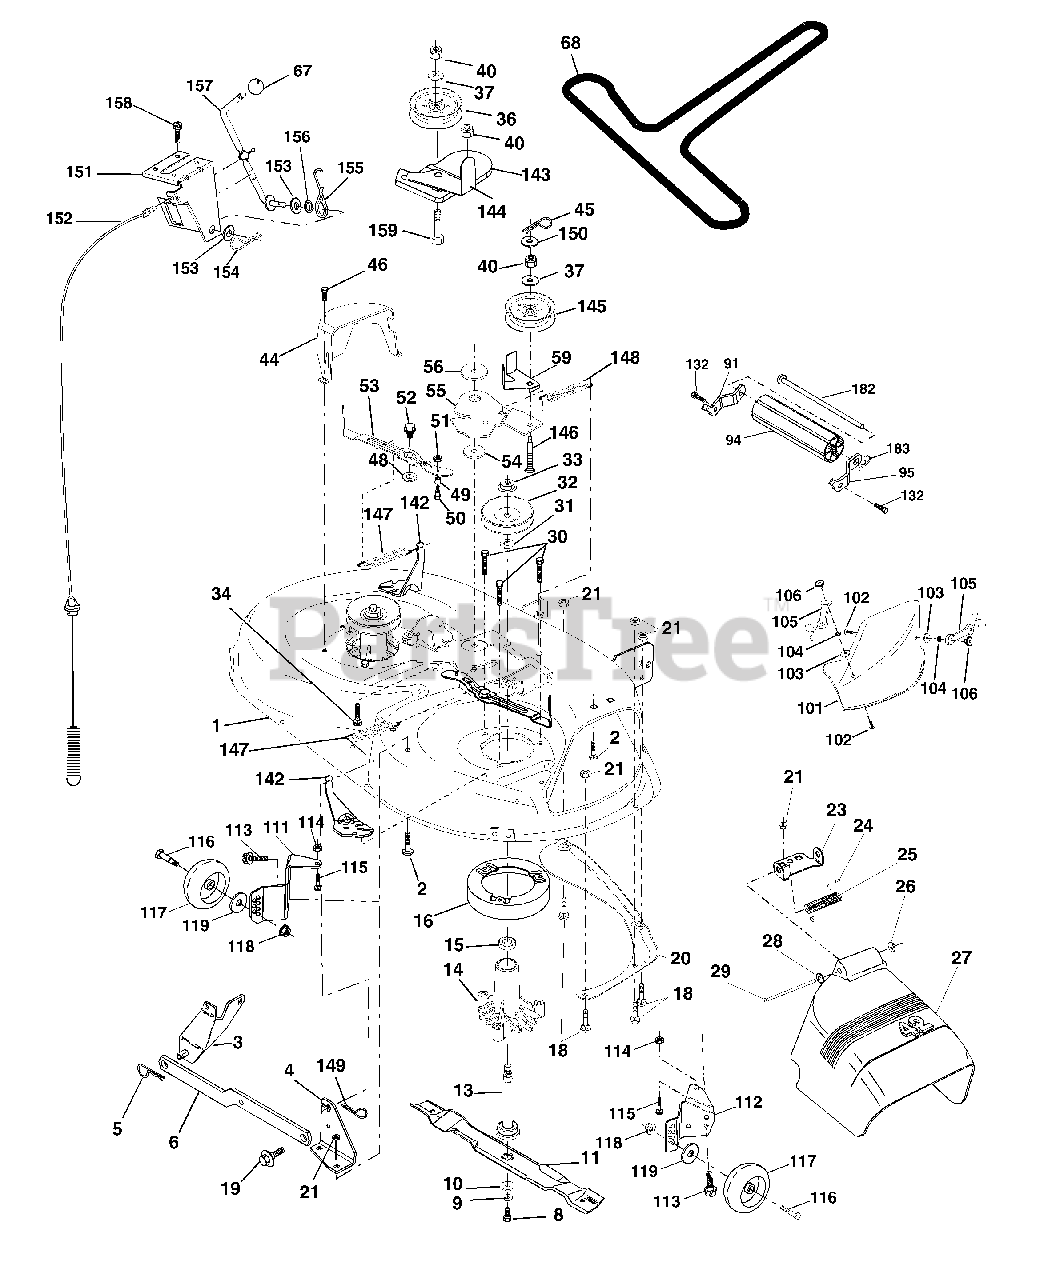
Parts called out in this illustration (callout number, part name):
1	Mower Deck Assembly, 42"
2	Bolt
3	Bracket Asm Fr. Sway Bar 3/42
4	Bracket Asm Deck 42" Sway Bar
5	Retainer Spring
6	Bar Sway Deck
8	Bolt 3/8-24 x 25 Gr. 8 patched
9	Washer, Lock
10	Washer, Hardened
11	Blade, Mulching 42" Std
11	Blade Mower 42" Hi-Lift Std
13	Shaft Assembly, Mandrel, Vented
14	Housing, Mandrel, Vented
15	Bearing, Ball, Mandrel
16	Stripper, Mower Deck
18	Bolt, Carriage 5/16-18 x 5/8
19	Bolt, Shoulder
20	Baffle, Vortex
21	Nut
23	Bracket, Deflector Mower 42"
24	Cap, Sleeve 80 x 112 Blk Mower
25	Spring, Torsion, Deflector 2 52
26	Nut, Push Phos & Oil
27	Shield, Deflector 42" Blk
28	Washer 11/32 x 5/8 x 16 Ga.
29	Rod, Hinge 42" 6 75 W/G
30	Screw Thdrol
31	Washer, Spacer Mower Vented
32	Pulley, Mandrel
33	Nut, Toplock 9/16
34	Bolt
36	Pulley, Idler, Flat
37	Washer 13/32 x 13/16 x 16 Ga.
40	Nut
44	Guard, Mandrel, LH
45	Retainer
46	Screw, Thdrol 1/4-20 x 5/8 T
48	Washer, Hardened
49	Roller Assembly, Cam Follower
50	Bolt, Shoulder #10-24 Grade 5
51	Locknut
52	Bolt, Shoulder 5/16-18 Unc
53	Arm Assembly, Pad, Brake
54	Washer, Hardened
55	Arm, Idler
56	Spacer, Retainer
59	Guard TUV Idler
67	Knob Round
68	V-Belt, 42" Mower
91	Bracket Roller Nose Lh
94	Roller Nose 38 & 42
95	Bracket Roller Nose Rh
101	Mulcher Cover
102	Screw Pan Hd Phillips 10-24 x 5/8
103	Washer, Flat
104	Washer, Lock
105	Latch Assembly
106	Nut, Weld
111	Bracket, Ga., Wheel LH
112	Bracket, Ga., Wheel RH
113	Screw 3/8-16 x .625
114	Nut, Keps 5/16 - 18 Unc
115	Bolt, Carriage 5/16-18 x 5/8
116	Bolt, Shoulder
117	Wheel, Ga.
118	Nut Centerlock 3/8-16
119	Washer 3/8 x 7/8 x 14 Ga.
121	Bracket, Extruded
132	Screw 3/8-16 x .75
142	Arm Spring Brake Mower
143	Bracket Arm Idler 42"
144	Keeper Belt 42" Clutch Cable
145	Pulley Idler Flat
146	Bolt Carriage Idler
147	Spring Extension
148	Spring Return Idler
149	Retainer Spring Yellow
150	Washer 9/32 x 3/4 x 16 Ga.
151	Bracket Clutch Cable
152	Clutch Cable 42"
153	Washer Flat 3/8" Type B
154	Spring Retainer
155	Spring Retention LVR CLTCH CAB
156	Spacer Clutch Cable
157	Rod Clutch Cable 3/8"
158	Screw Hex Thd Cut 1/4-20 x 1/2
159	Bolt Rdhd Sqn 3/8-16 Unc x 1-3/4
182	Rod Roller Nose
183	Retainer Spring
